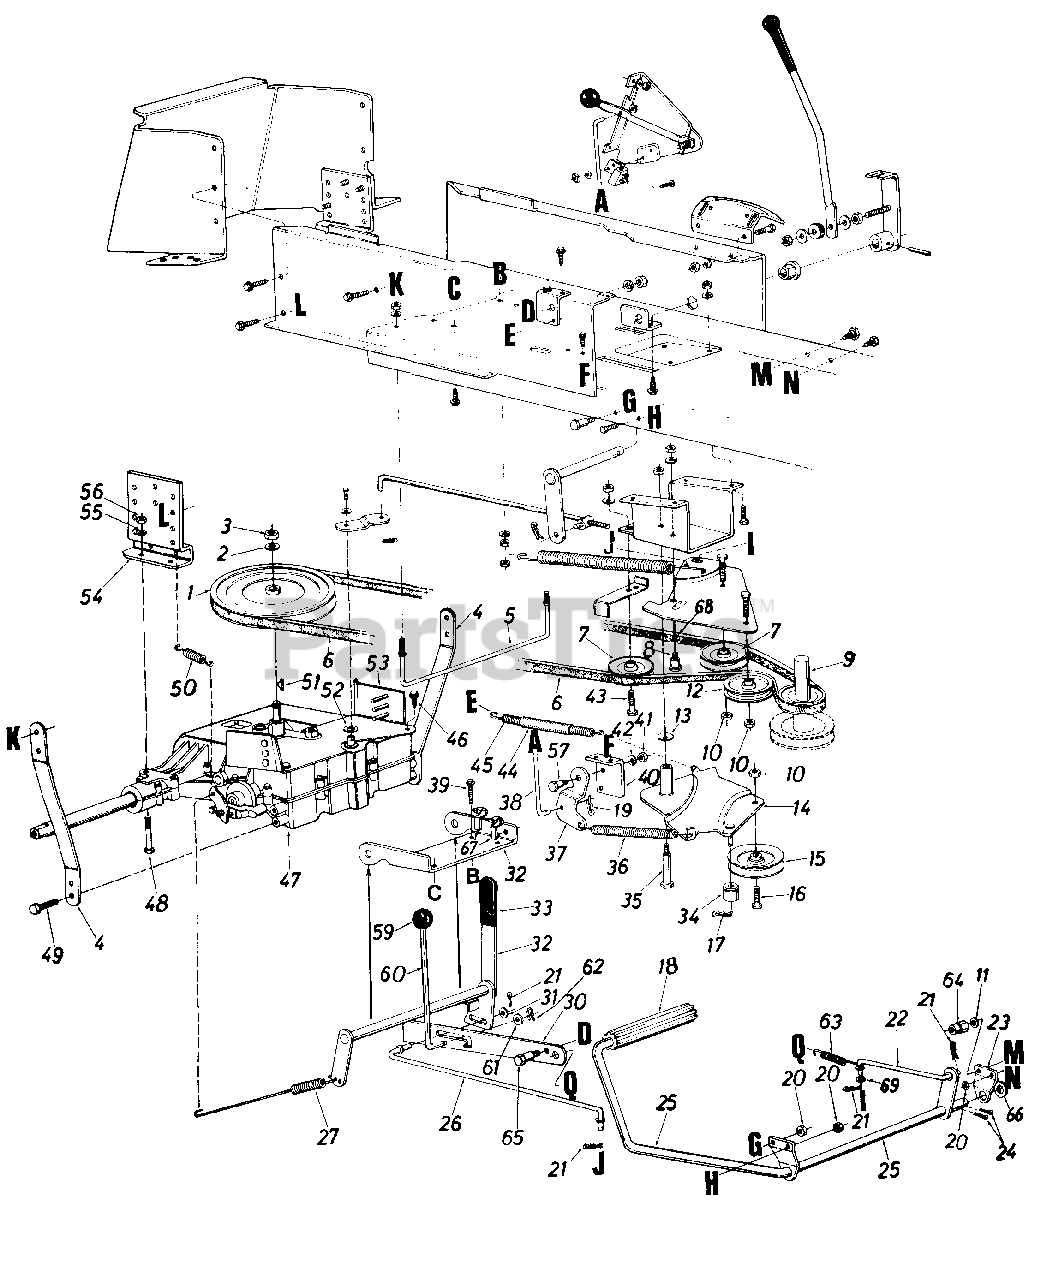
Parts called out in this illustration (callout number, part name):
1	8" "V"-Pulley
2	L-Wash. 1/2" I.D.
3	Hex Nut 1/2-20 Thd.
4	Transaxle Brace
6	'IV"-Belt
7	"V"-Belt Idler Pulley .38" I.D. x 3-1/16" O.D.
8	Shoulder Bolt .435" Dia. x .160 (5/16-18)
9	Two Step Engine Pulley 3.10" & 5.56" Dia.
10	Hex Nut 3/8-16 Thd.
11	L-Wash. 3/8" I.D.
12	Flat Idler Pulley 2.75" O.D.
13	Belleville Wash. .400" I.D. x .88" O.D. x .063
14	Idler Bracket Ass'y.
15	4" "V"-ldler Pulley
16	Hex Bolt 3/8-24 x 1.5" Lg.
17	Hairpin Cotter 5/16" Dia.
18	Foot Pad
19	Intern. Cotter Pin 5/16" Dia.
20	Hex Cent. L-Nut 3/8-16 Thd.
21	Hairpin Cotter 3/32" Dia. x 3/4" Lg
22	Brake Clutch Rod (4.60" Lg.)
23	Clutch Rod Bearing Brkt.
24	Cotter Pin 118" Dia. x 1.00"
25	Clutch Brake Pedal Ass'y.
26	Brake Cam Rod (13.60" Lg.)
27	Extension Spring .59" O.D. x.93" Lg.
30	Parking Brake Cam
31	Fl-Wash. .406" I.D. x 1.00" O.D. x .030 Thk.
32	Hand Brake Lever Ass'y.
33	Grip-Flat Bar 11/4" Wide
34	Spacer
35	Shoulder Bolt .496" Dia. x 2.00" Lg. (3/8-16)
36	Extension Spring .751" O.D. x6.12" Lg.
37	Deck Control Brkt.
38	Deck Control Rod
39	Hex Wash. Hd. TT-Tap Scr. 1/4-20 x 1.50" Lg.
40	Parking Brake Cam Mtg. Brkt.
41	Hex Nut 5/16-18 Thd.*
42	L-Wash. 5/16" I.D.*
43	Hex Bolt 3/8-24 x 1.50" Lg. (Grade 5)
44	Convoluted Conduit .50" I.D. x 4.0" Lg.
45	Ext. Spring .50" O.D. x 6.37" Lg.
46	Hex Wash. Hd. AB 0 Tap Scr. 5/16-18 x 5/8" Lg.
47	Transaxle
48	Hex Bolt 5/16-18 x 2.50" Lg.*
49	Hex Wash. Hd. AB 0 Tap Scr. 5/16-18 x 5/8" Lg.
50	Extension Spring .50" O.D. x 2.75" Lg.
51	Hi-Pro Key 3/32" x 5/8" Dia.
52	Special Wash. 1.00" O.D. (Hdn.)
53	Transaxle Belt Keeper Ass'y.
54	Transaxle Support Bracket
55	L-Wash. 5/16" I.D.*
56	Hex Nut 5/16-18 Thd.*
57	Shoulder Bolt .437" Dia. x .162" Lg. (5/16-18)
60	Parking Brake Link
61	Fl-Wash.
62	Hairpin Cotter
63	Ext. Spring 3.12" Lg.
64	Spacer Nut 3/8-16 Thd.
65	Shld. Bolt .435" Dia. x .16"
66	Fl-Wash. .53" I.D. x .93" O.D.
67	Plastic Hose Clamp
68	Spr. Wash. .445" I.D. x .75" O.D.
69	Fl-Wash. .385" I.D. x.62" O.D.
